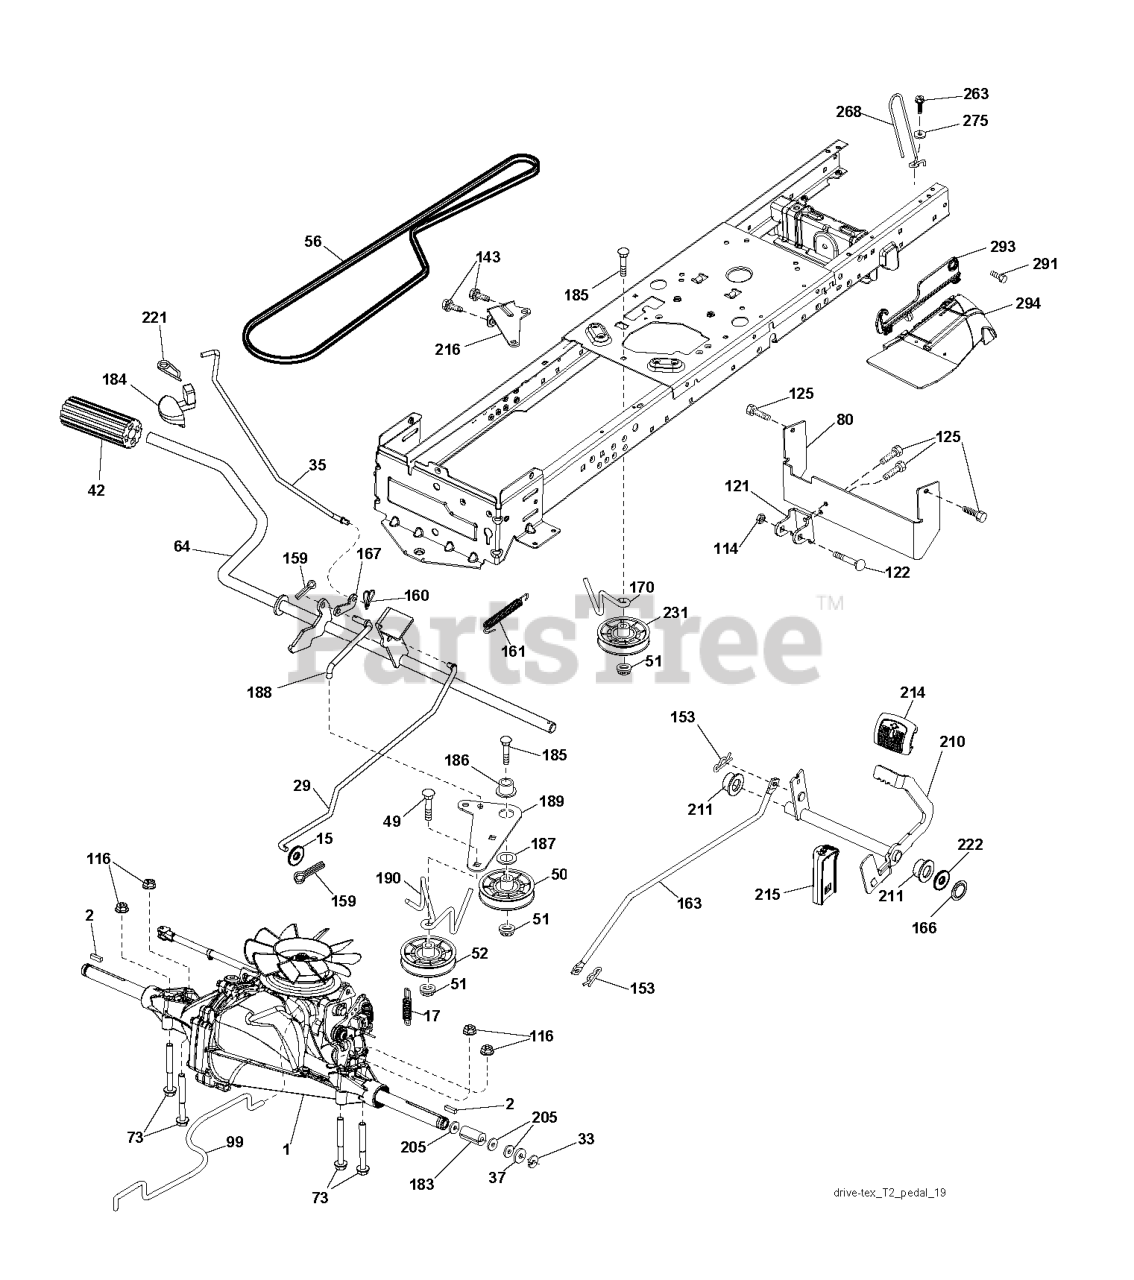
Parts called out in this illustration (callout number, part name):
2	SQUARE KEY
15	WASHER
17	SPRING.BRAKE.HG3000/3500
29	ROD.BRAKE.T2.TEX
35	ROD.CNTRL.PARK.PREDATOR.LT.TEX
42	PEDAL COVER T
50	IDLER.FLAT.910.OFFSET
51	NUT LOCK FLG 3/8-16 UNC
52	IDLER.V-GROOVE.910.OFFSET
64	SHAFT.ASM.PEDAL.BRK.CNTR
73	BOLT HEX 5/16-18 GR 5
80	RP.STRAP.TORQUE.FS.T2
99	ROD.ASM.BYPASS.SPRING.T2.FS
114	NUT.71038.31-18.HEX.NYLOCK
116	NUT LOCK HEX FLANGE 5/16-18
121	BRACKET STRAP TORQUE
122	BOLT.5/16-18X2.5
125	SCREW
143	Screw 5/16-18 x 1/2 Hex, Self Tapping 5/16-18 x 1/2
153	RETAINER M
159	COTTER PIN
160	RETAINER CLIP
161	SPRING, RETURN LT
163	ROD.CONTROL.PCH.T2.TEX
166	NUT.PUSH.625.2006
167	LATCH.BRAKE.SPRING
170	KEEPER.CENTER SPAN.1.688
183	SPACER, AXLE PVST
184	HANDLE PARKING BRAKE
186	SPACER.RETAINER
187	WASHER 12/32X2X10GA
188	RP.LINK.CLUTCH.GROUND.DRIVE
189	BELLCRANK.GROUND.DRIVE.TEX.
190	KEEPER.BELLCRANK.DRIVE
210	ROCKER.ASM.PEDAL.CONTR
211	BEARING.NYLON
214	PEDAL.FORWARD.PAD.TEX
215	PEDAL.REVERSE.TEX.GT.4
216	BRACKET.PULLEY.IDLER.W/TEX
221	RETAINER.SPRING.CLIP.H
222	WASHER 21/32 X 1-1/4 X 10 GA.
231	IDLER.V-GROOVE.1.688.OFFSET
263	SCREW, 3/8-16X3/4
268	GUARD MUFFLER
275	WASHER
291	SHOULDER BOLT 5/16-18TT
293	HINGE RIGHT
